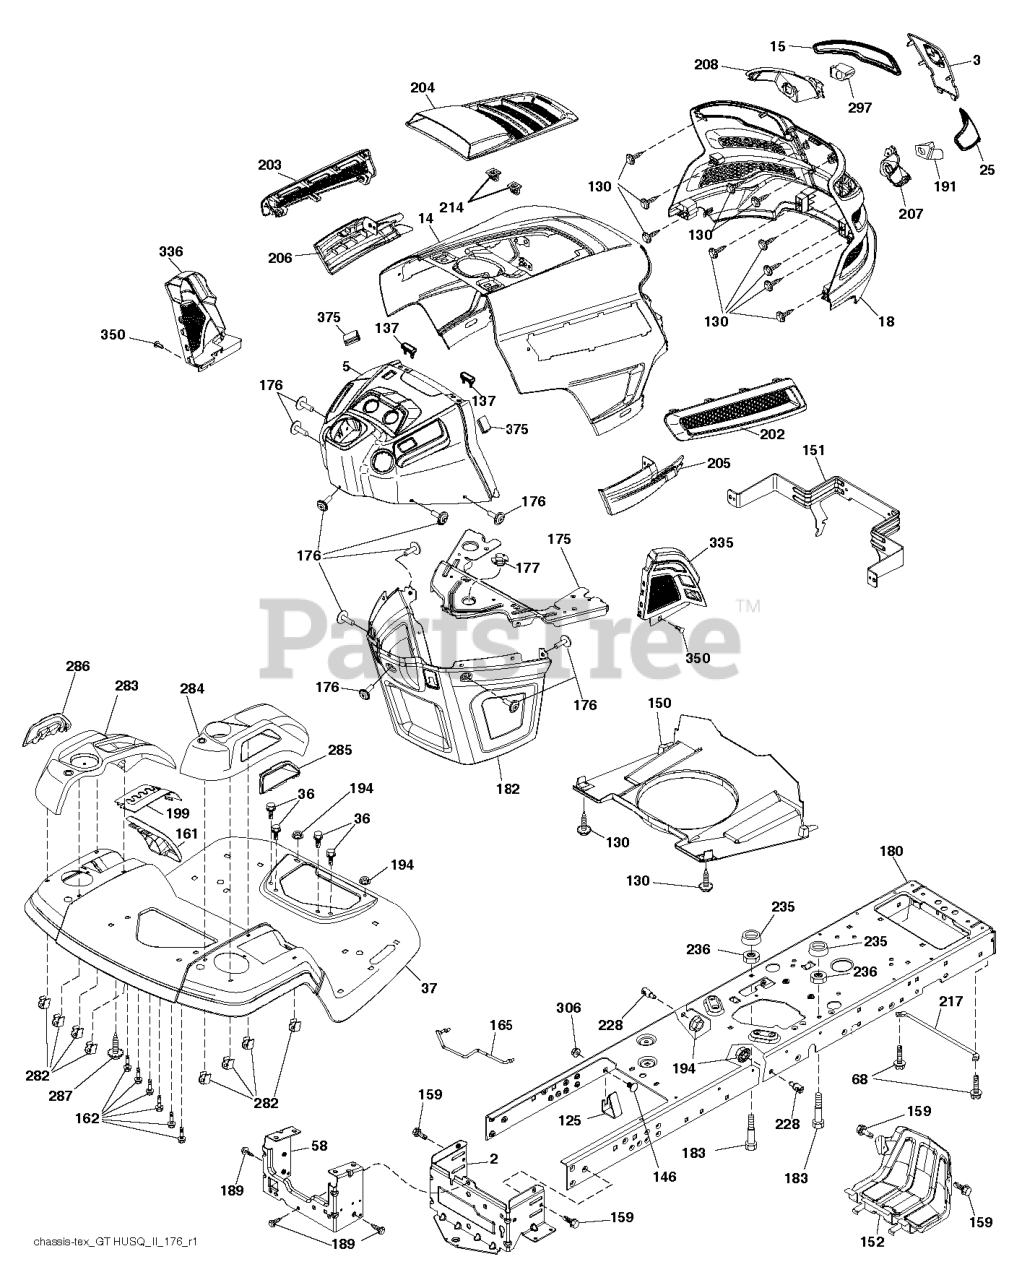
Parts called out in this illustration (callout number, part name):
2	BRACKET, FRAME
12	LEVER (FLEX. LEVER)(RPLS -13)
18	HANDLE COMP
39	RING, SNAP, M62 x 2.0
48	WHEEL GEAR
